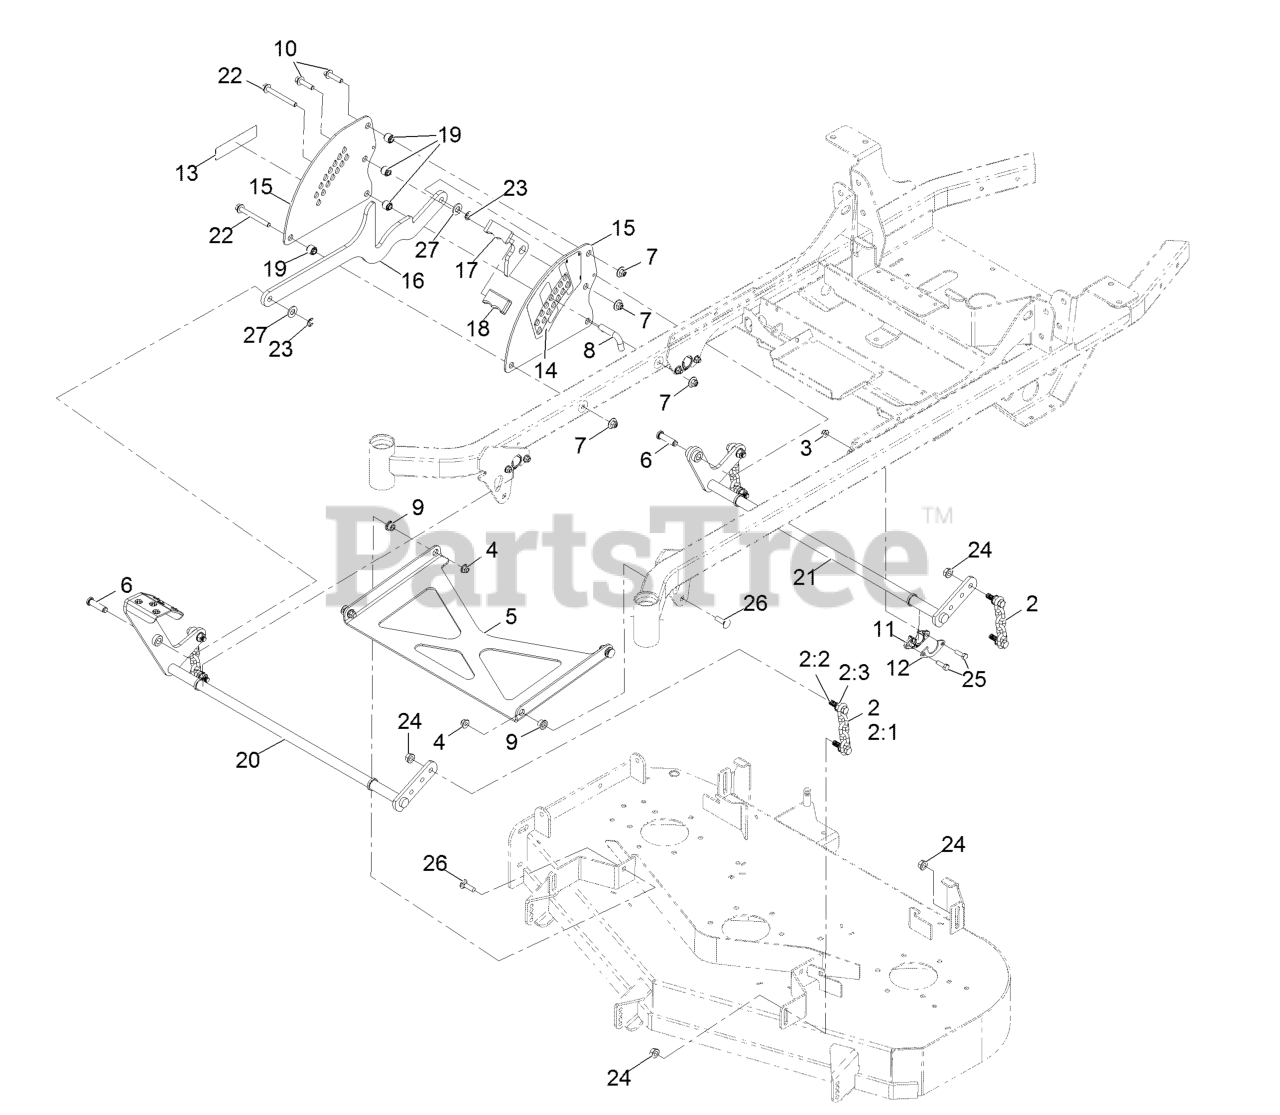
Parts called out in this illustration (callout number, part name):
2	DECK CHAIN ASM
2:1	CHAIN-LIFT, DECK
2:2	SCREW-HH
3	NUT-HF, NI
4	NUT-HF, NI
5	STRUT-DECK
6	PIN-CLEVIS
7	Nut-Nyloc 3/8-16 Flg
8	PIN-HOC
9	BUSHING-FLANGED
10	SCREW-HHF
11	BUSHING-FLANGE
12	GUSSET-LIFT, DECK
13	DECAL-S-SERIES
14	DECAL-HEIGHT OF CUT
15	PLATE,DECK LIFT
17	TRANSPORT LOCK-HOC
18	GRIP-FLAT
19	SPACER-STEP, DOUBLE
20	WLD-DECK LIFT SHAFT FRT
21	WLD-DECK LIFT SHAFT RR
22	SCREW-HHF
23	RING-RETAINING, EXTERNAL
25	SCREW-HH
26	BOLT-CARR
27	WASHER-FLAT
